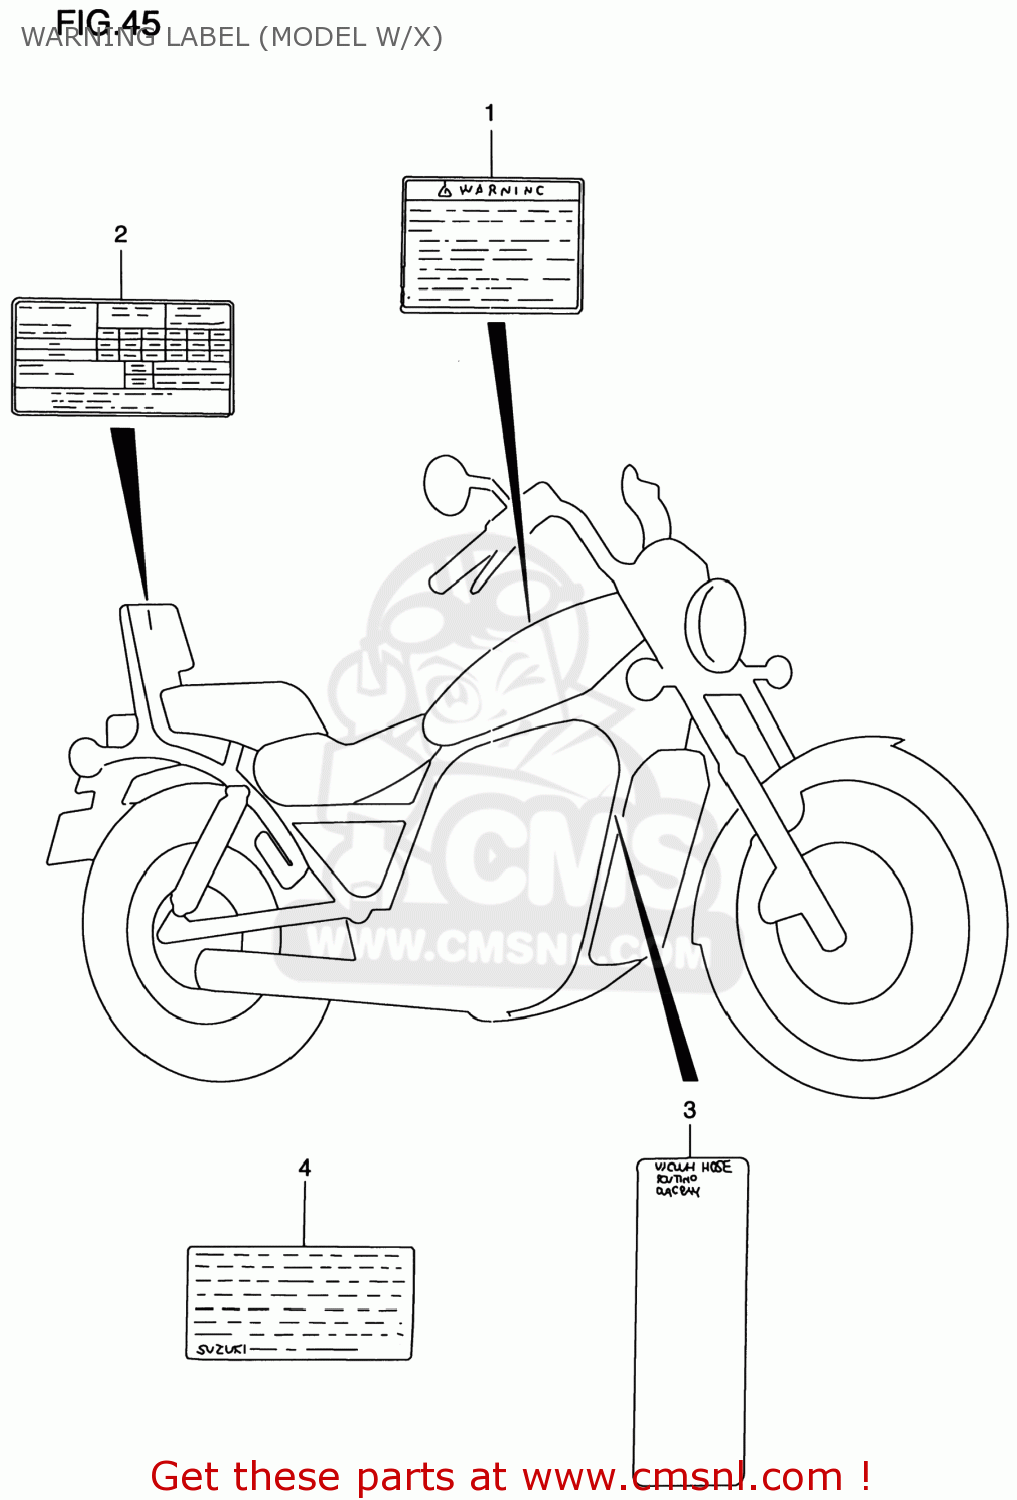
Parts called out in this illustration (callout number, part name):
1	LABEL (WARNING SAFETY),E
2	LABEL (TIRE INFORMATION)
3	LABEL (VACUUM HOSE ROUTING)
4	LABEL (MANUAL NOTICE)
5	MANUAL, OWNER'S
